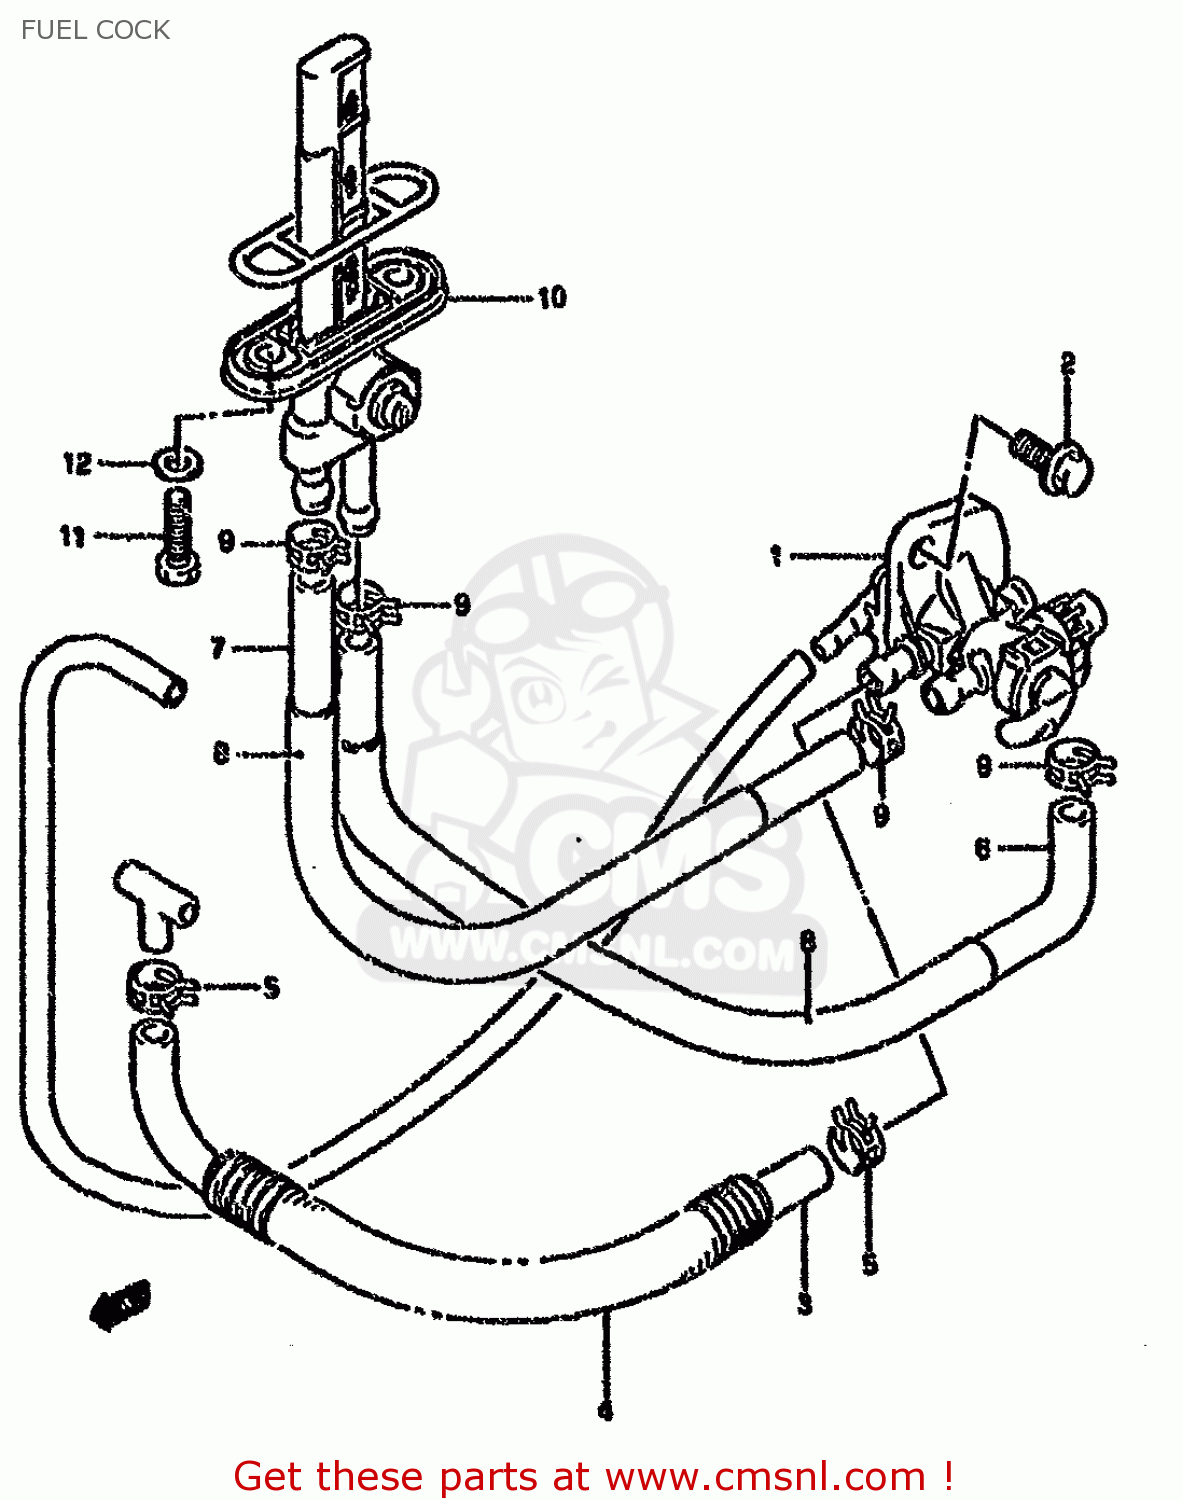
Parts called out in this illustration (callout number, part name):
1	COCK ASSEMBLY,FUEL
2	BOLT
3	HOSE(7X11X600)
4	TUBE,FUEL HOSE
5	CLIP
6	HOSE(7X11X600)
7	HOSE,FUEL RESERVE
8	PROTECTOR,FUEL HOSE
9	CLIP
10	COCK ASSY,FUEL NO.1
11	O RING,FUEL COCK
12	BOLT(6X20)
13	GASKET(6.4X11.5X0.8) (NAS)
